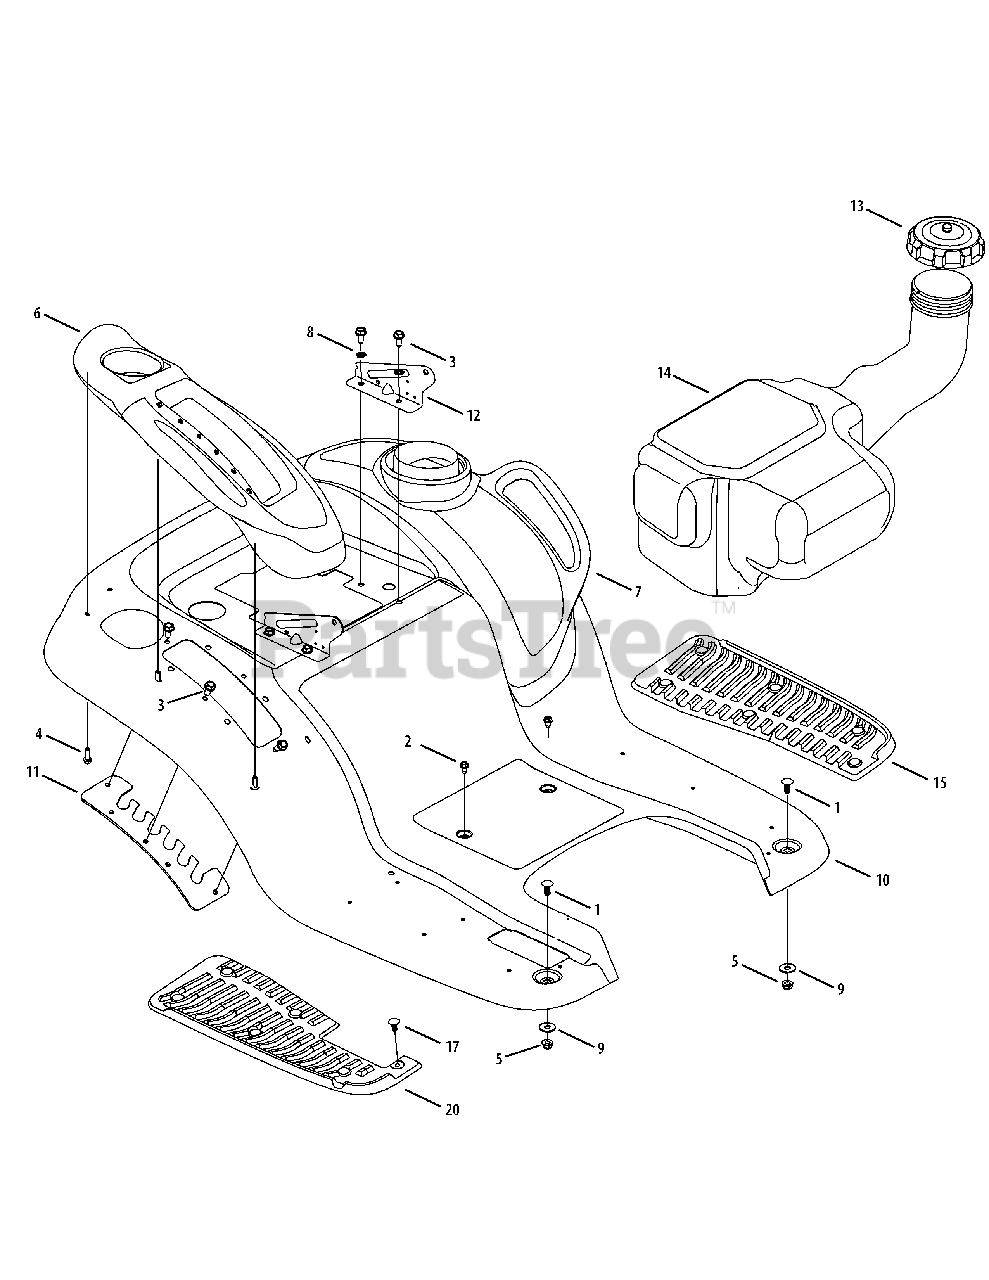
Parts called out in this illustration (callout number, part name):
1	Bolt, Carriage, 5/16-18 x .750
2	Screw, Self-tapping, 1/4-20, 0.500
3	Screw, 5/16-12, 0.75
4	Screw, 1/4-15, 0.750
5	Nut, Nylon Lock, 5/16-18
6	Cover, Fender, RH
7	Cover, Fender, LH
8	Washer, Lock, 5/16 External Tooth
9	Washer, Flat, .349 x 1.00 x .063
13	Cap, Fuel
14	Tank, Fuel
15	Pad, Foot, LH
16	Pad, Foot, RH
17	Clip, Ratchet, .250 Dia
